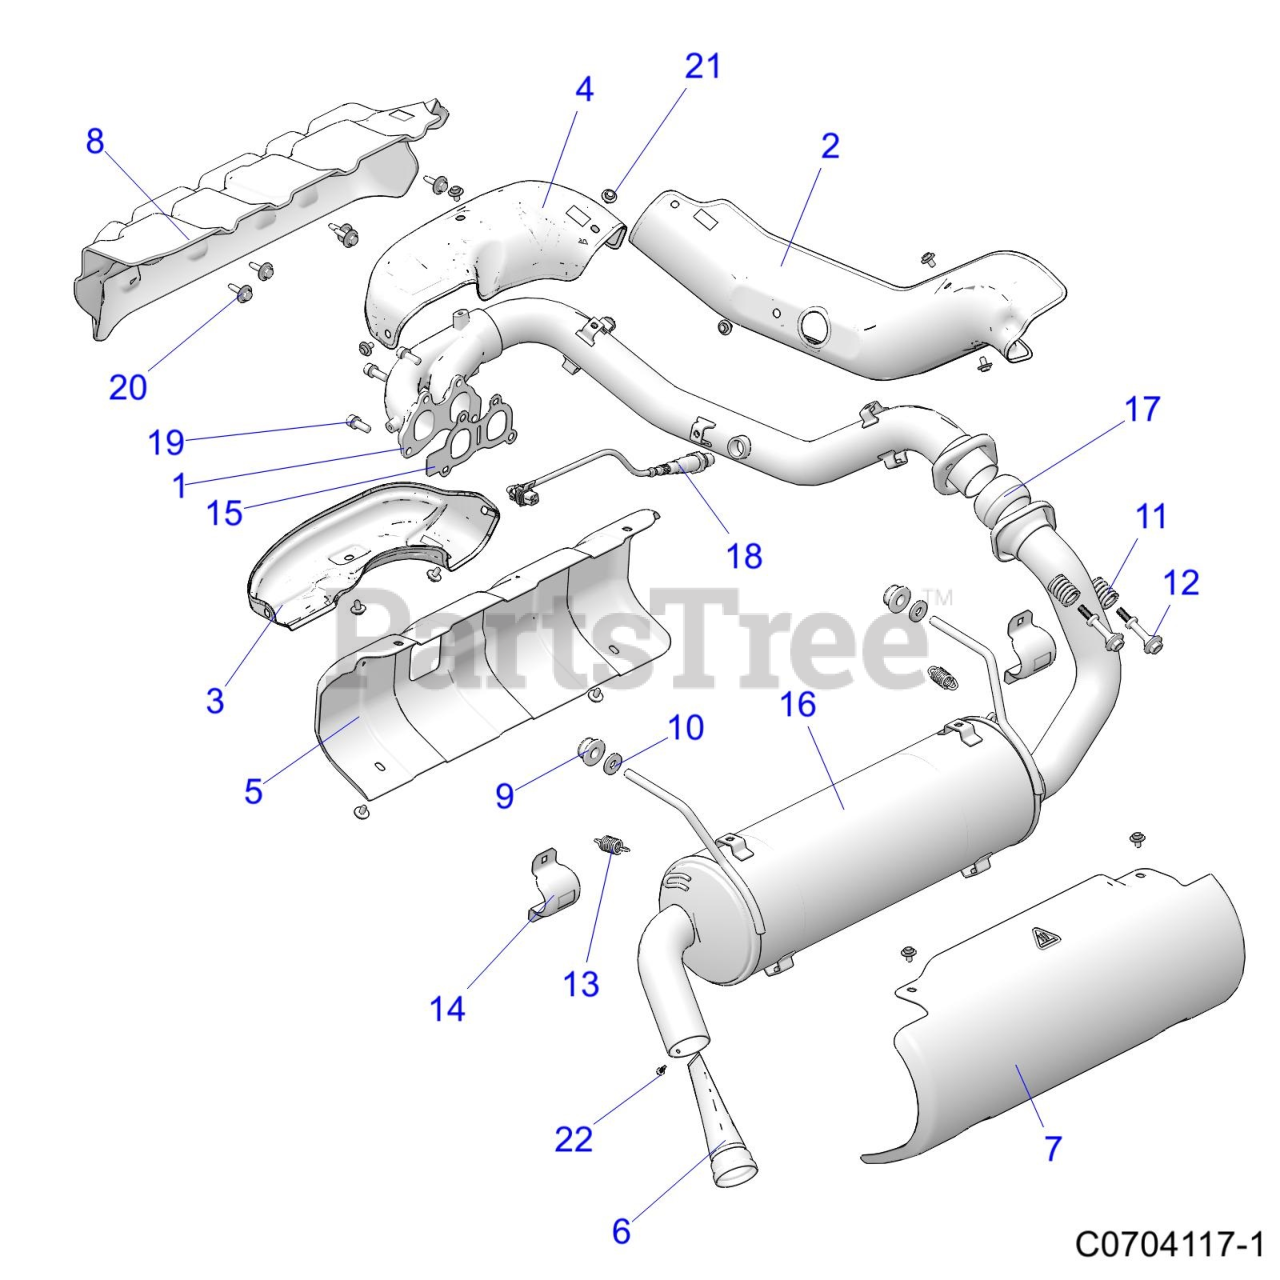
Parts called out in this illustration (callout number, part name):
1	ASM-HEADPIPE
2	SHIELD-HEAT,SILENCER,INNER
3	SHIELD-HEAT,HEADPIPE,FRONT,UPR
4	SHIELD-HEAT,HEADPIPE,INNER
5	SHIELD-HEAT,SILENCER,INNER
6	WELD-SPARK ARRESTOR
7	SHIELD-HEAT,SILENCER,OUTER
8	SHIELD-HEAT,CLOSEOFF
9	ISOLATOR-EXHAUST,HANGER
10	WASHER-.406X1.00X.125,FL
11	SPRING-SPHERICAL,EXHAUST
12	STUD-SPHERICAL,EXHAUST
13	SPRING-EXHAUST S.S. SHOTPEENED
14	SHIELD-BUSHING,SWAY BAR
15	GASKET-EXHAUST SEAL
16	ASM-SILENCER,RGR
17	GASKET-DOUBLE SPHERICAL,2"
18	SENSOR-LAMBDA,LSF 4.2
19	SCR-M8X1.25X22,HX/SO
20	SCR-HXFL-M6X1.0X25 8.8 ZPB SEM
21	SCR-HHSEMS-M6X1.0X10 A286,LOCK
22	SCR-HXFL-M6X1.0X10 8.8
